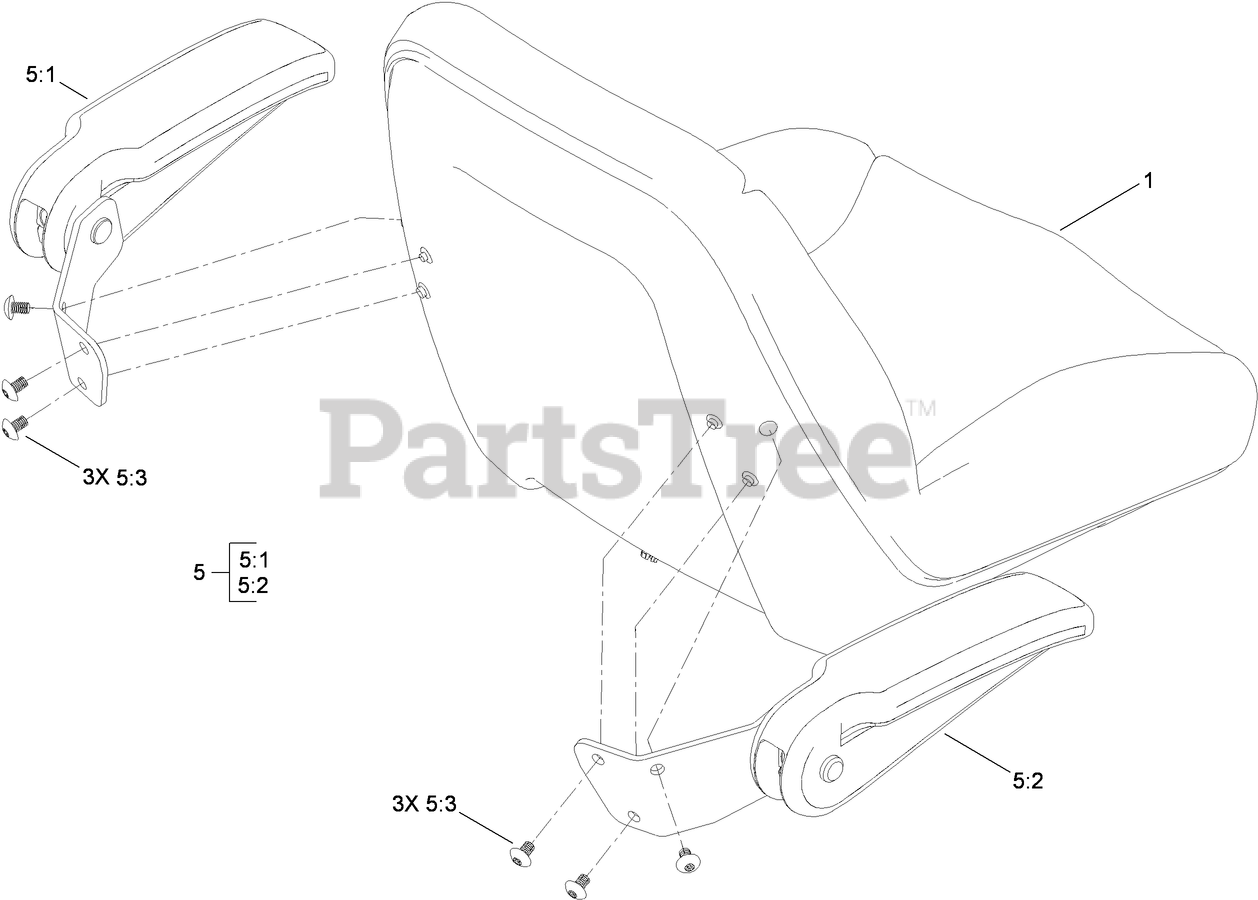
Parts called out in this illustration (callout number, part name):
1	SEAT-18 INCH
5	ARMREST KIT
5:1	LH ARMREST KIT
5:2	RH ARMREST KIT
5:3	SCREW-HSBH
